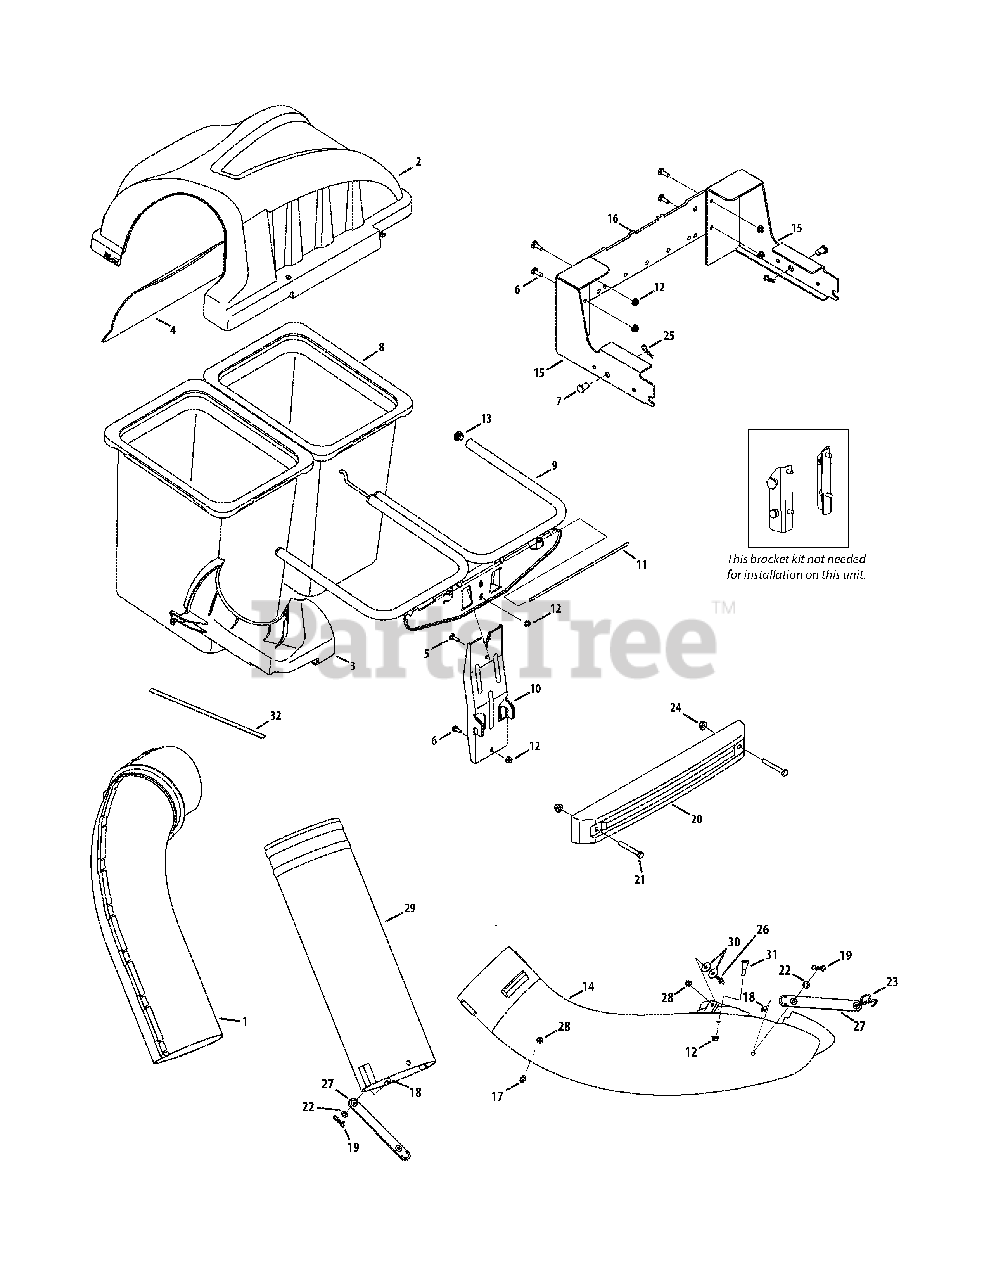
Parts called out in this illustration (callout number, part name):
1	Upper Chute Assembly
2	Twin Bagger Cover Assembly
3	Upper Chute Support
4	Bagger Cover Screen
5	Carriage Screw, 5/16-18 x 1.00"
6	Hex Head Screw, 5/16-18 x .75"
7	Clevis Pin, .50" Dia.
8	Grass-bag Assembly
9	Twin Bag Support Assembly
10	Vertical Support Bracket
11	Cover Hinge Pin
12	Flange Lock Nut, 5/16-18
13	End Plug
14	Discharge Chute Elbow
15	RZT Hitch Bracket Kit
17	Grass-catcher Pin
18	Clevis Pin 5/16 x 3/4
19	Bow-Tie Cotter Pin
20	Bagger Weight
21	Hex Head Screw, 3/8 - 16 x 2.75
22	Flat Washer, .344 x .62 x .033
23	Torsion Spring Hook
24	Flange Lock Nut, 3/8 - 16
25	Cotter Pin, .080 x 1.5625 Internal
26	Grass-catcher Pin
27	Chute Strap
28	Flange Lock Nut, 1/4-20
29	Bagger Chute Adapter, 7 In.
30	Flat Washer
31	Shoulder Screw
32	Foam Strip
